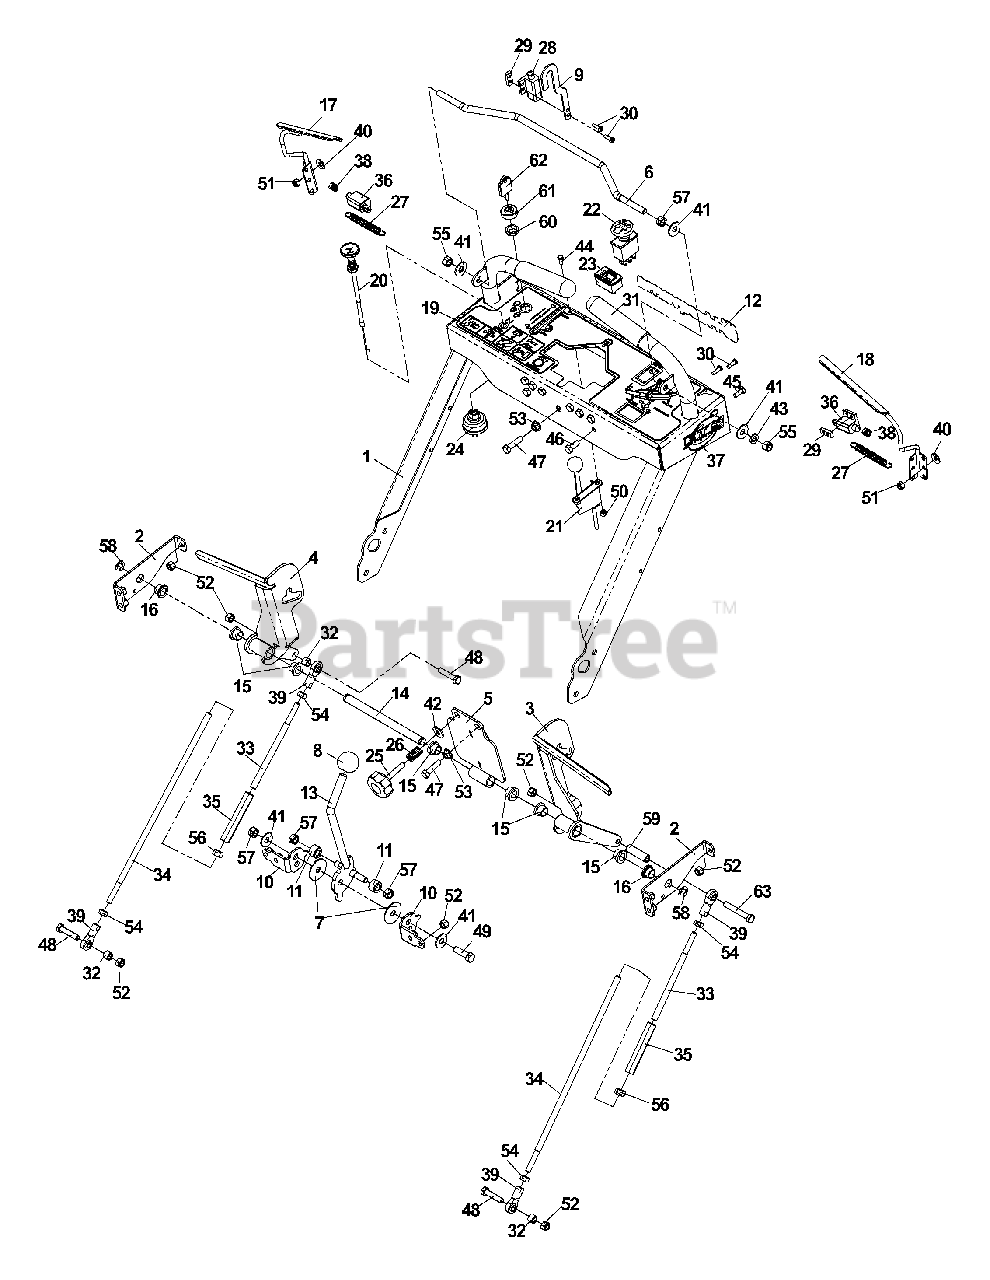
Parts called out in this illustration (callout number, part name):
1	HANDLE
3	DRIVE LEVER, LEFT
4	DRIVE LEVER, RIGHT
5	TRACKING PLATE
7	WASHER, FRICTION
8	KNOB, SHIFT
9	ARM, NEUTRAL
10	PLATE, FRICTION
12	DECAL, HUSQVARNA
13	LEVER, GROUND SPEED
14	SHAFT, CROSS
15	BUSHING, NYLON FLANGED
16	BUSHING, FLANGED
19	DECAL, CONSOLE
20	CONTROL, CHOKE
21	CABLE, THROTTLE
22	SWITCH, CLUTCH
23	HOURMETER
24	SWITCH, IGNITION
25	KNOB, ADJUSTMENT
28	SWITCH, N.C.
29	PLATE, TAPPED
30	SCREW, #10-24 X 5/8, MACHINE
32	SPACER, PULLEY
33	LINKAGE, SHORT
34	LINKAGE, LOWER
35	TURNBUCKLE, 3/8
36	SWITCH N.C.
37	DECAL, ETS
38	SPRING, SWITCH
39	BALL END, RIGHT
40	WASHER, 1/4
41	WASHER, 3/8
42	WASHER, 5/16
43	LOCKWASHER, 3/8
44	HCS, #10-24 X 1/2
45	HCS, 1/4-20 X 5/8
46	HCS, 5/16-18 X 3/4
47	HCS, 5/16-18 X 1 1/4
48	HCS, 5/16-18 X 1 1/2
49	HCS, 3/8-16 X 1 1/4
50	NUT, #10-24, NYLOC
51	NUT, 1/4-20, NYLOC
52	NUT, 5/16-18, NYLOC
53	NUT, 5/16-18
54	NUT, 5/16-24
55	NUT, 3/8-16, NYLOC
56	NUT, 3/8-24
57	NUT, 3/8-16, CENTER LOCK
58	E-RING, 1/2"
60	NUT, IGNITION SWITCH
61	CAP, IGNITION SWITCH NUT
62	KEY, PADDED GRIP
63	HCS, 5/16-18 X 2 3/4
